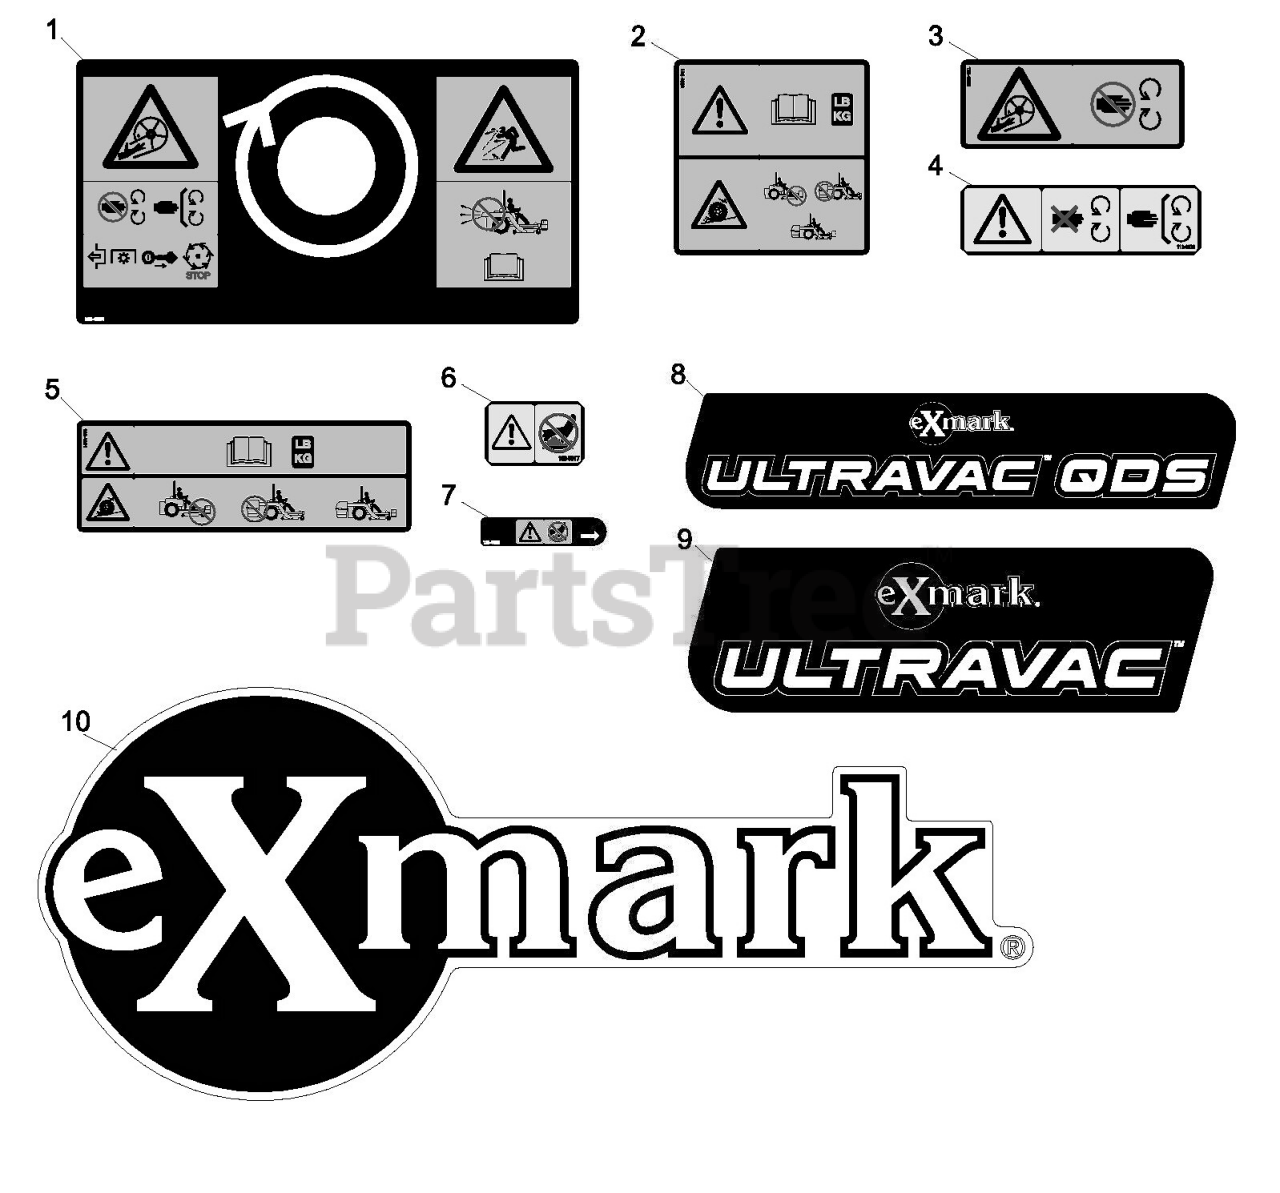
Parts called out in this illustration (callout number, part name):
1	Decal-Warning Blower
2	Decal-Warning Traction
3	Decal-Blower Impeller Hazard
4	Decal-Cover Missing
5	Decal-Warning Weight
6	Decal-Hot Surface
7	Decal-Hot Pulley
8	Decal, UltraVac QDS
9	Decal, UltraVac
10	Decal-Exmark (60 & 72)
